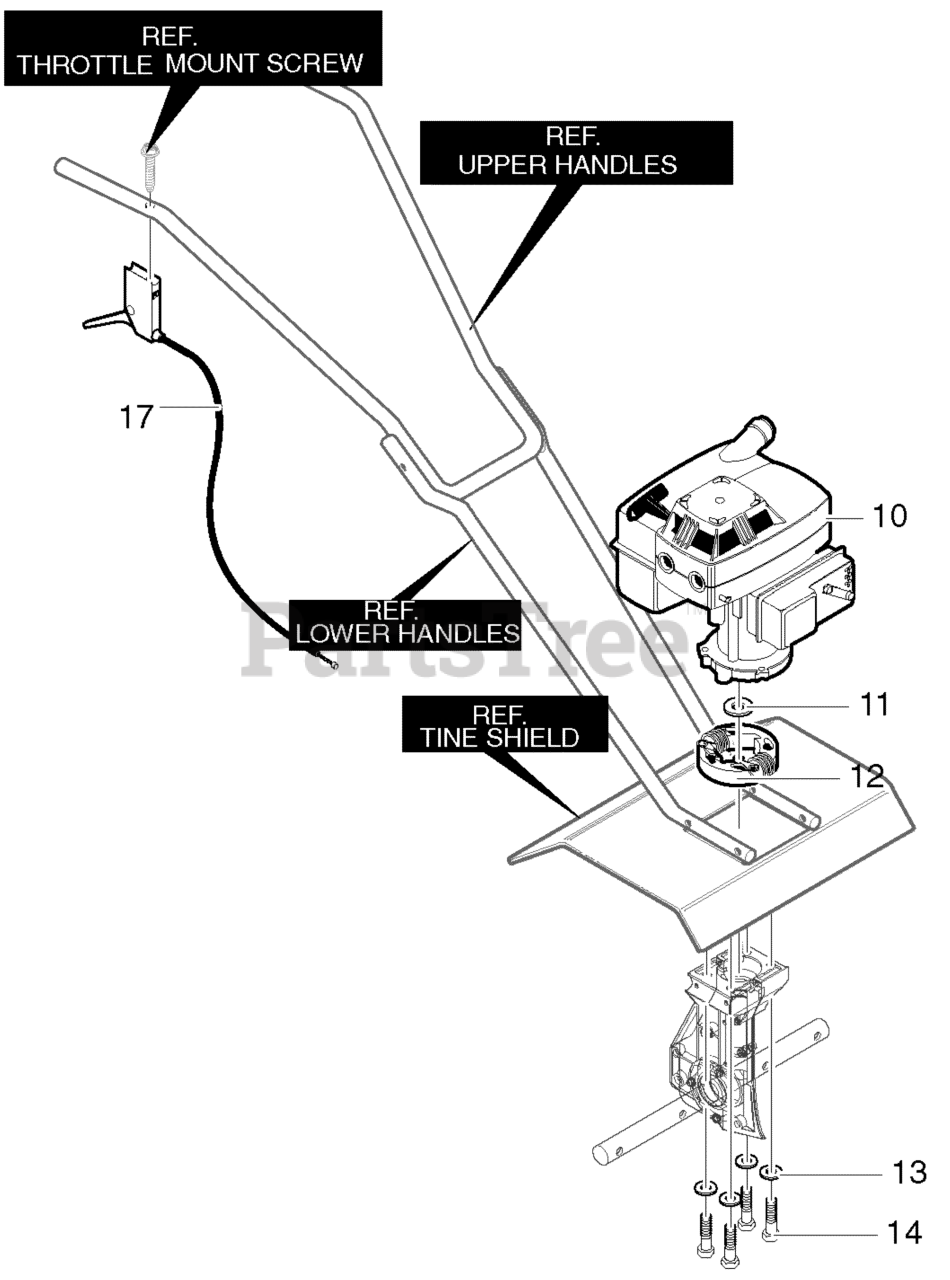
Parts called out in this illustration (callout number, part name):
10	Engine 143.042070
11	Flat washer
13	Washer
17	Cable, Throttle
